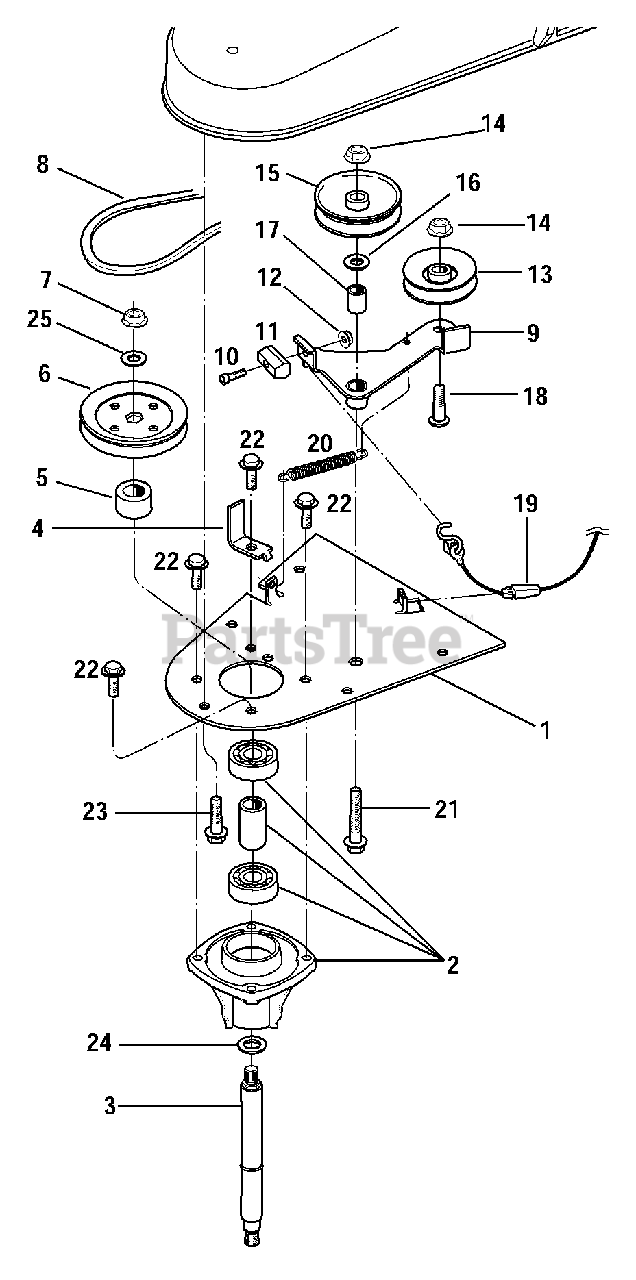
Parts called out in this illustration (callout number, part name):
1	Spindle Mounting Plate
2	Spindle Assembly
3	Spindle Shaft Assembly
5	Spindle Spacer
6	Spindle Pulley
7	Hex Flange Nut, 1/2-13
9	Idler Arm/Brake Shoe Assembly
10	Socket Hd Capscrew, 10-24 x 3/4
11	Brake Shoe
12	Hex Lock Nut, 10-24
13	V-Groove Idler Pulley
14	Hex Flange Nut, 3/8-16
15	Flat Idler Pulley
16	Washer, .88 x .382 x .275
17	Idler Arm Spacer
18	Button Head Screw, 3/8-16 x 1-1/2
19	Control Cable
20	Idler Tension Spring
21	Hex Flange Screw, 3/8 x 16 x 2-1/4
22	Hex Flange Screw, 5/16-18 x 3/4
23	Hex Flange Screw, 5/16-18 x 1
24	Hardened Shim, 3/4 ID x 1.022 OD x .060 thick
25	Belleville Washer, 5/8
